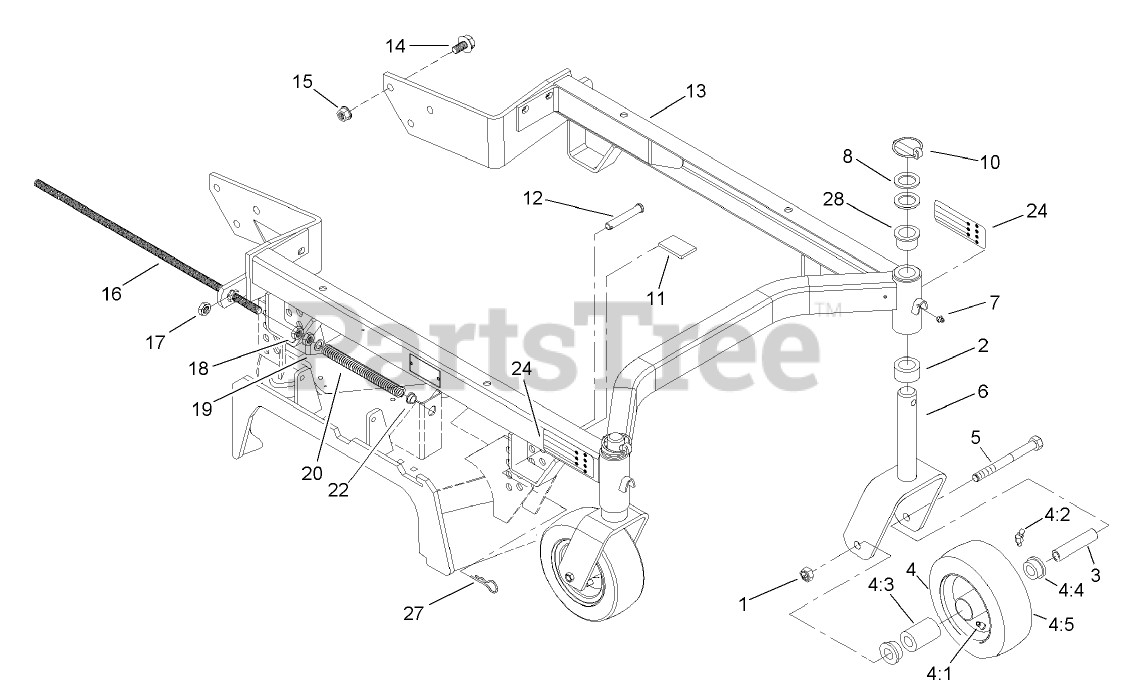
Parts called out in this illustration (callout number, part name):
1	NUT-HEX
2	SPACER-CASTOR
3	BUSHING-SPANNER
4	CASTER WHEEL ASM
4:1	STEM-VALVE
4:2	FITTING-LUBE, 45 DEG
4:3	BEARING
4:4	BEARING-OUTSIDE
4:5	TIRE-TUBELESS
5	SCREW-HH
6	CASTOR FORK ASM
7	FITTING-GREASE
8	WASHER-THRUST
10	PIN-LYNCH
11	CUSHION-RUBBER
12	PIN-CLEVIS
13	44IN CARRIER FRAME ASM
14	SCREW-HHF
15	NUT-HF
16	SHAFT-ADJUSTING
17	NUT-LOCK, NI
18	NUT-JAM
19	WASHER
20	SPRING
22	BUSHING-FLANGE
24	DECAL-HOC
27	PIN-HAIR
28	BUSHING
